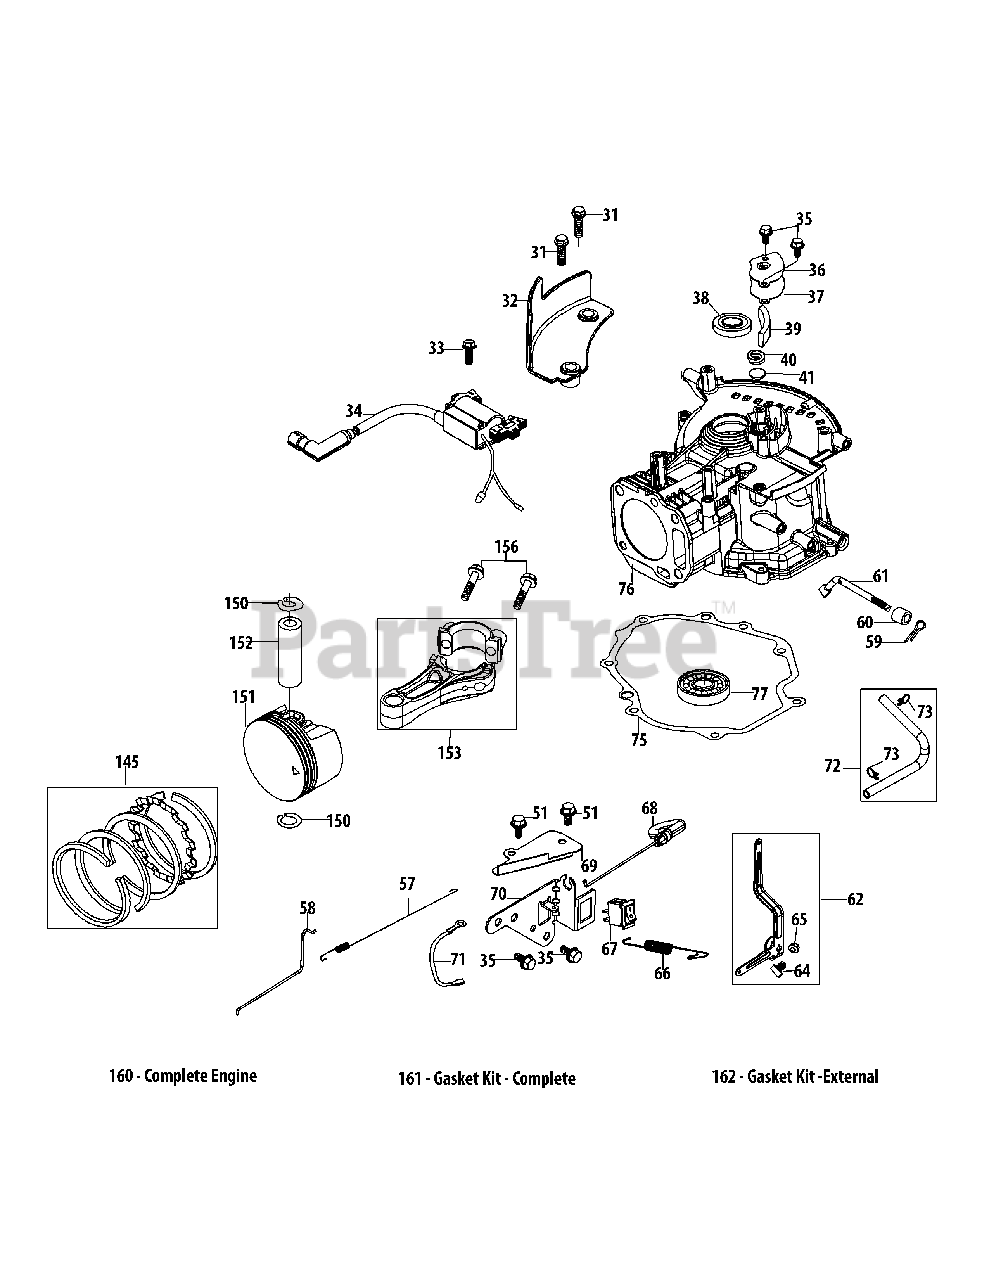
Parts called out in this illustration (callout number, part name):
31	Bolt M6×25 Cover Plate
32	Engine Brake Cover Plate
33	Bolt M6×20 Ignition Coil
34	Ignition Coil Assembly
35	Bolt M6X14 Multi-Purpose
36	Breather Cover Plate
37	Breather Gasket
38	Upper Crankshaft Seal
39	Breather Screen
40	Breather Valve Spring
41	Breather Valve
51	Bolt M6X12 Multi-Purpose
57	Throttle Linkage Spring
58	Throttle Linkage
59	Governor Arm Shaft Cotter Pin
60	Governor Seal
61	Governor Arm Shaft
62	Governor Arm Assembly
64	Governor Arm Bolt
65	Governor Arm Nut M6
66	Governor Spring
67	Ignition Switch
68	Choke Control
69	Air Vane Cover Plate
70	Component Bracket
71	Ignition Switch Ground Wire
72	Breather Hose Assembly
73	Breather Hose Clamp
75	Crankcase Cover Gasket
76	Short Block
77	Main Bearing
145	Piston Ring Set
150	Piston Pin Snap Ring
151	Piston
152	Piston Pin
153	Connecting Rod Assembly
156	Connecting Rod Bolt
160	Complete Engine
161	Gasket Kit - Complete
162	Gasket Kit -External
